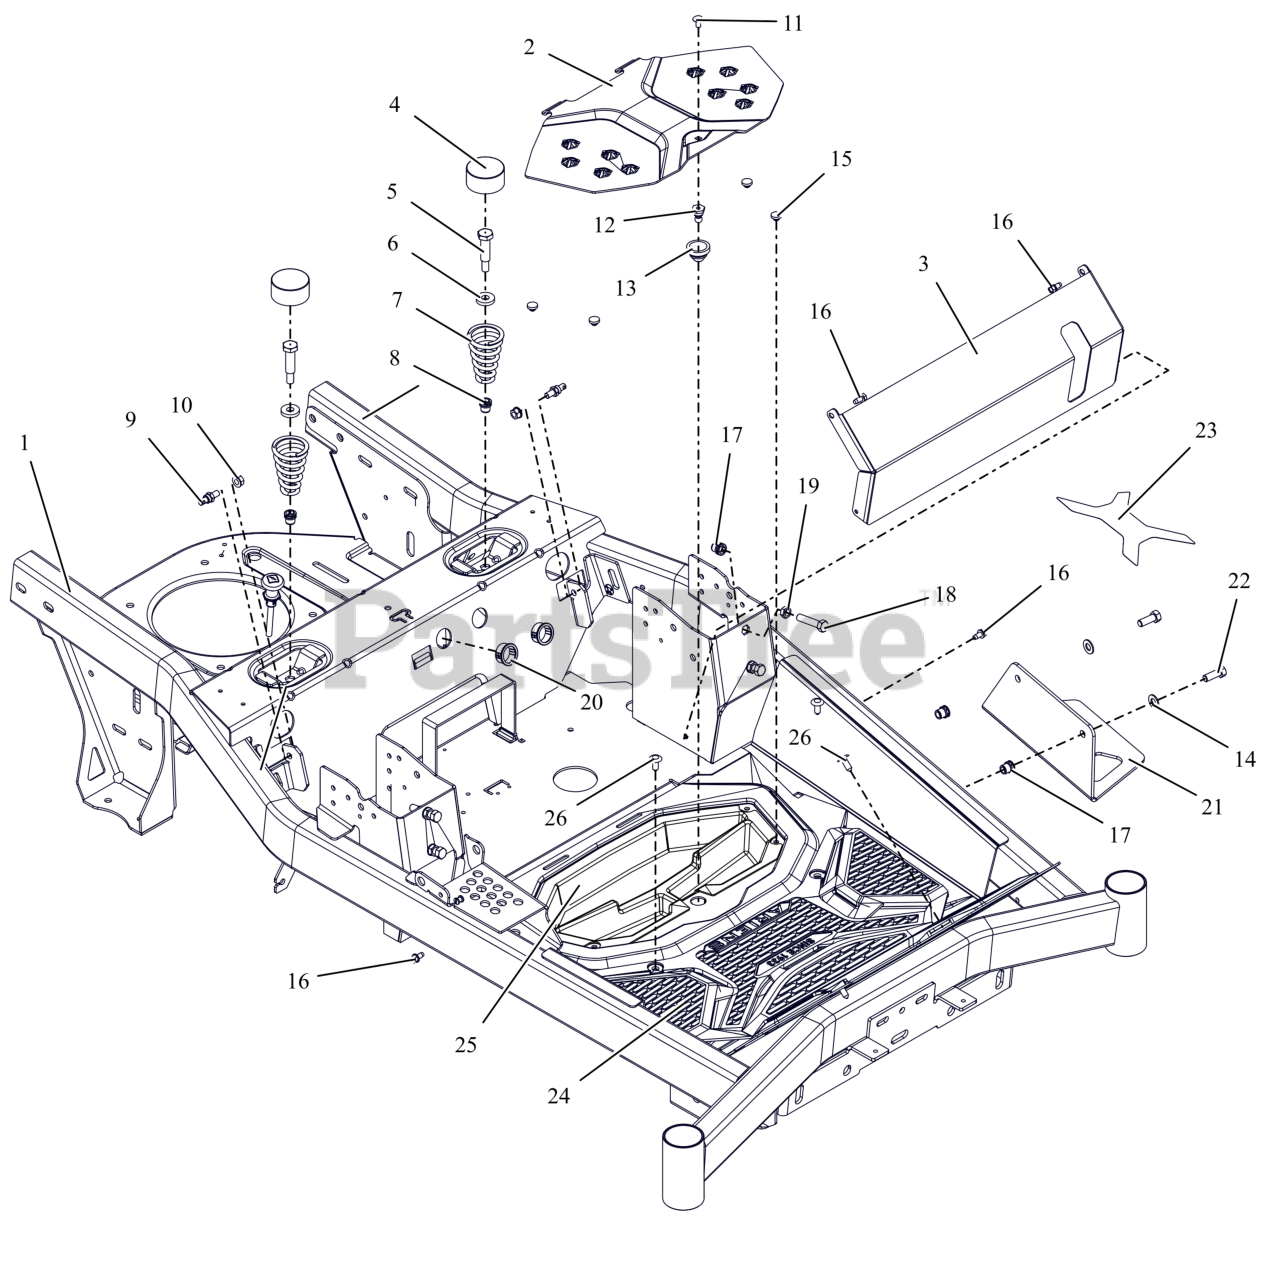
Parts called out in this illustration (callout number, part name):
1	KIT,ARIENS FRAME W/ DECALS
2	KIT, ARIENS ACCESS PLT W/DECAL
3	PLATE, FRONT KICK (BLACK)
4	HUB CAP
5	BLT-SHLDR .50X1.50 .375-16 ZCC
6	WSHR, FLT .406X1.00X.188 ZCC
7	SPRING, SEAT
8	NUT,THD,INSERT .38-16 ZC120
9	COUPLER, DAMPER MOUNT
10	NUT-LK-TOP-FLG .312-18 GF ZCC
11	BLT, RHSSN.25-20X.500 G5 ZCC
12	STUD, BALL FEMALE .250-20 THREAD
13	COUPLING, RUBBER PUSH-IN
14	WSHR,FLT .406X.812X.065 ZCC
15	BUMPER GROMMET
16	SCR-TAP .25-20X.50 HWH ZCC
17	NUT,THD,INSERT .38-16 ZC120
18	BLT, HEX .38-16X1.75F G5 ZCC
19	NUT-JAM .375-16 G2 ZCC
20	BSHG, PANEL SNAP .937X1.11X.56
21	STEP, (ORANGE)
22	BLT, HEX .38-16X1.00 G8ZCCEP30
23	GRIP- TAPE - STEP -ARIENS
24	MAT- RUBBER FOOTBOARD- IKON
25	INSERT, GRAVELY STORAGE
26	XMAS TREE FASTNER-BLACK
